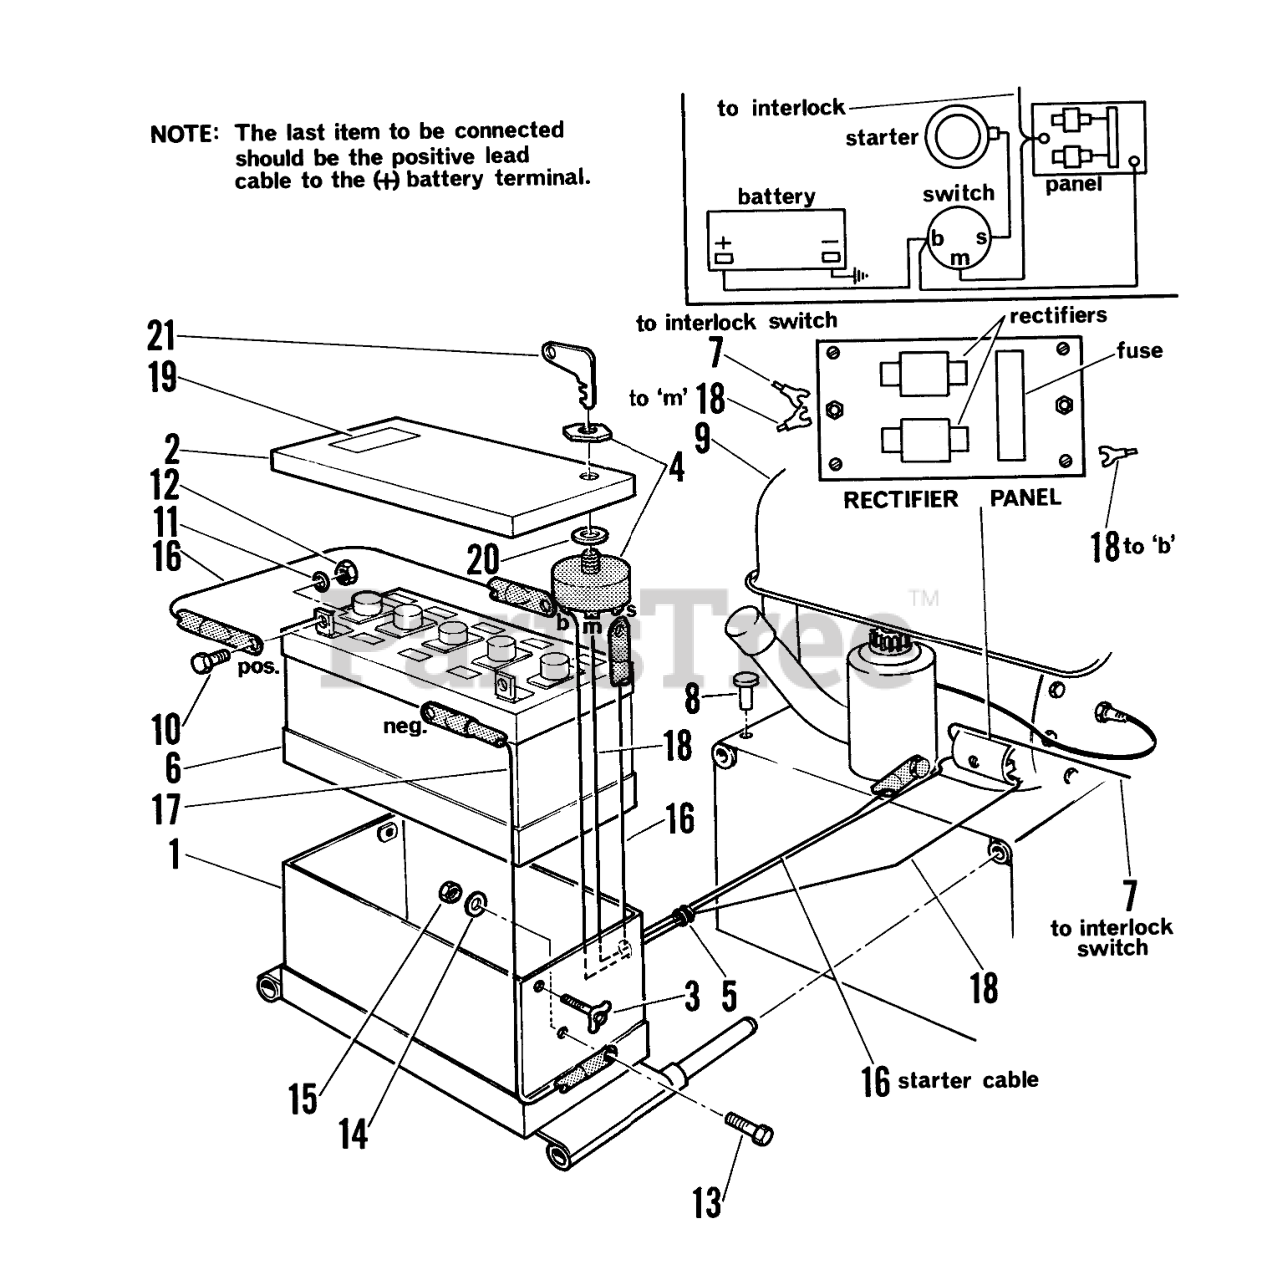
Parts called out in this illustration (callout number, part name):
1	Battery Box
2	Cover-Batt. Box
3	Thumb Screw
4	Switch
5	Grommet
6	Battery-12 Volt
7	Wire (To interlock switch)
9	Engine 6 H.P. Elec. Start
10	SCREW-HH
11	WASHER-LOCK
12	NUT-HEX
13	SCREW-HH
14	WASHER-LOCK
15	NUT-HEX
19	Decal
20	Washer
